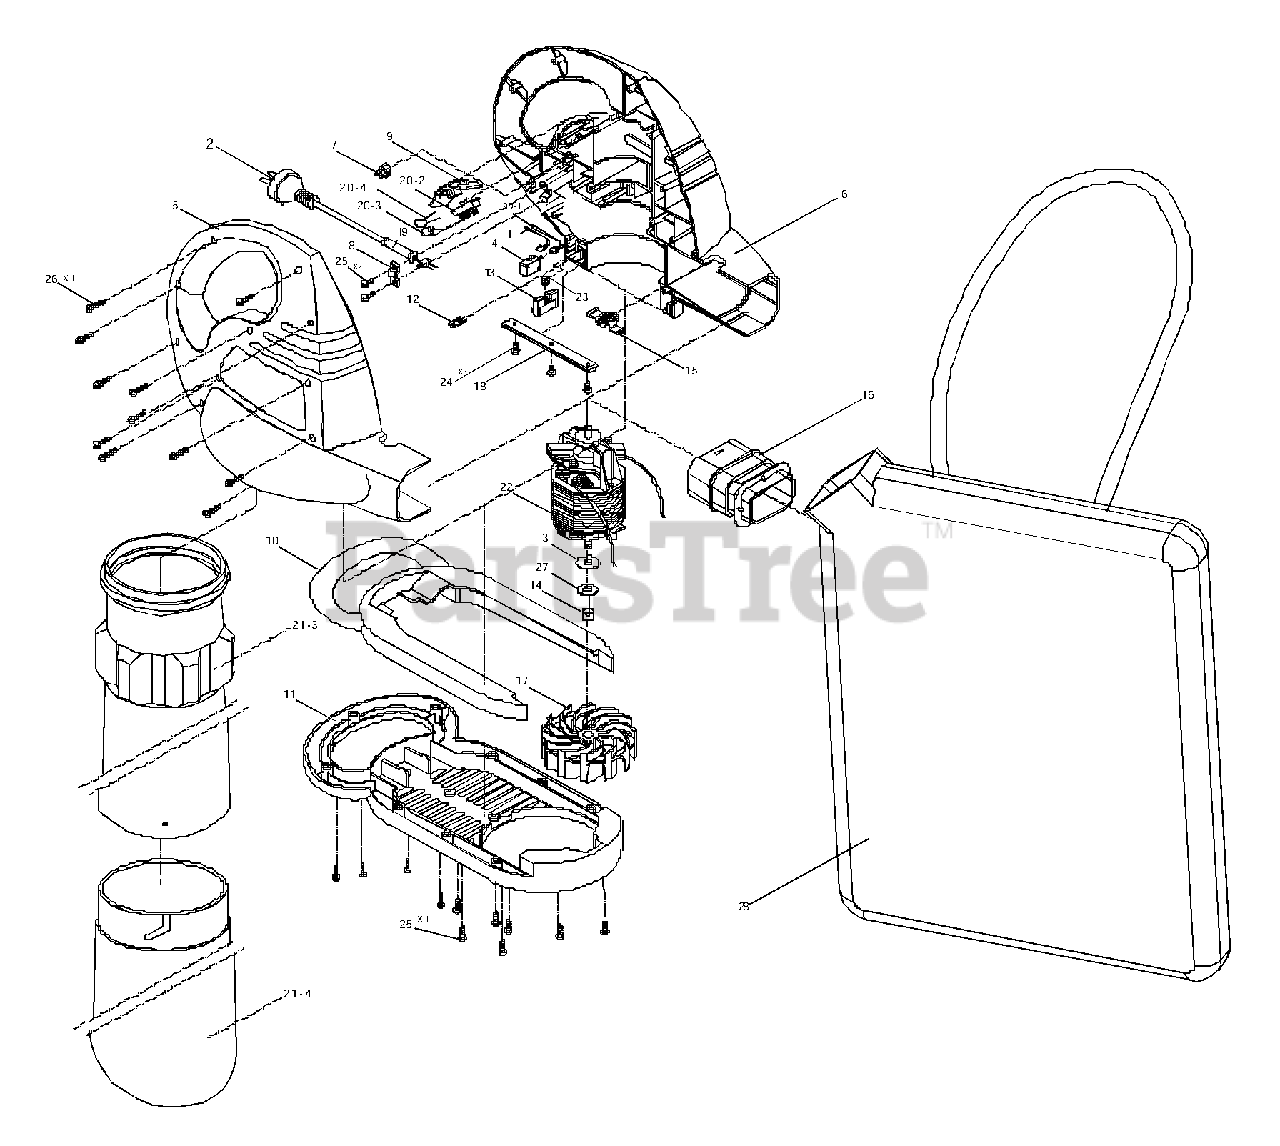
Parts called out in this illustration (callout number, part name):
2	POWER CORD
5	HOUSING (L)
6	HOUSING (R)
7	TERMINAL BLOCK
8	STRAIN RELIEF
10	UPPER HANDLE
11	LOW HANDLE
12	SPRING PLATE
13	SAFETY SHAFT
14	SHAFT SLEEVE
16	CONNECTING PIPE
18	TRANSMISSION SHAFT
19	CORD GUARD
20	SWITCH ASS'Y
21	ABSORTING TUBE ASS'Y
22	MOTOR 120V
